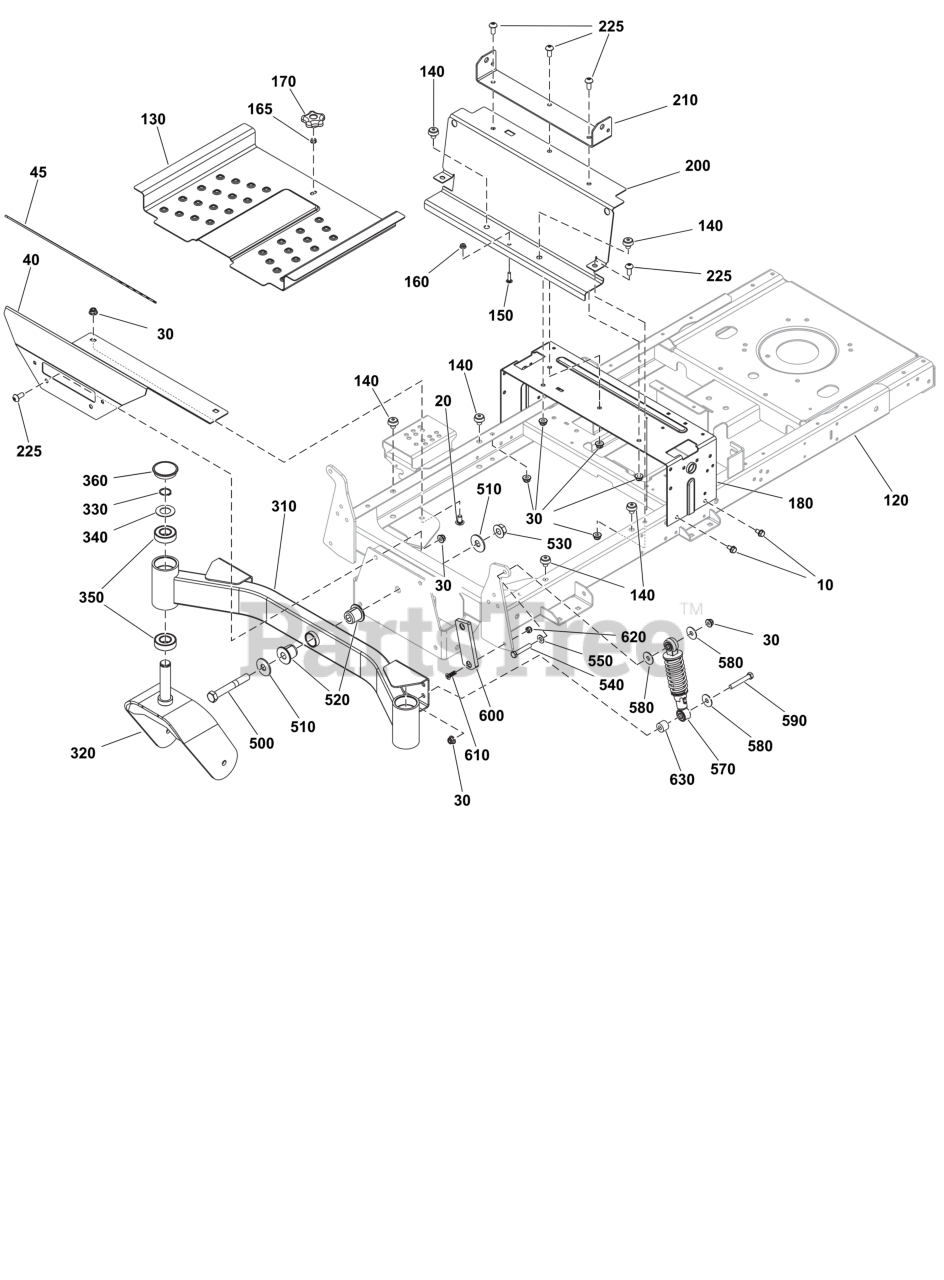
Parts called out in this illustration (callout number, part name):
10	SCREW, 5/16-18.625
20	BOLT, 3/8-16X.75 G5
30	NUT, 3/8-16 HEX NYLOCK
40	FOOTREST, FRONT
45	SAFETY WALK, 8.00 X 1
120	WELDMENT, ZT XT FRAME-FULL SUSP(FER R)
130	PAN, Foot
130	FOOT PAN W/DECAL, EXPORT 2019 (1757813B)
140	MOUNT-VIBRATION
150	RHSSNB, 1/4C X1 GR5 Z
165	NUT,25-20 HEX FLG CTR
180	BRACKET, CONTROL
200	PLATE-DECAL
225	CAPSCREW
320	YOKE, Caster
330	RETAINER, EXT RING, 1
340	WASHER, 1
510	WASHER-0.625(0.64IDX1
540	CAPSCREW, 3/8-16X2
570	ABSORBER, Shock
580	WASHER, 3/8" FENDER
600	PAD-FRICTION
610	SCREW, 5/16-18 X 1
